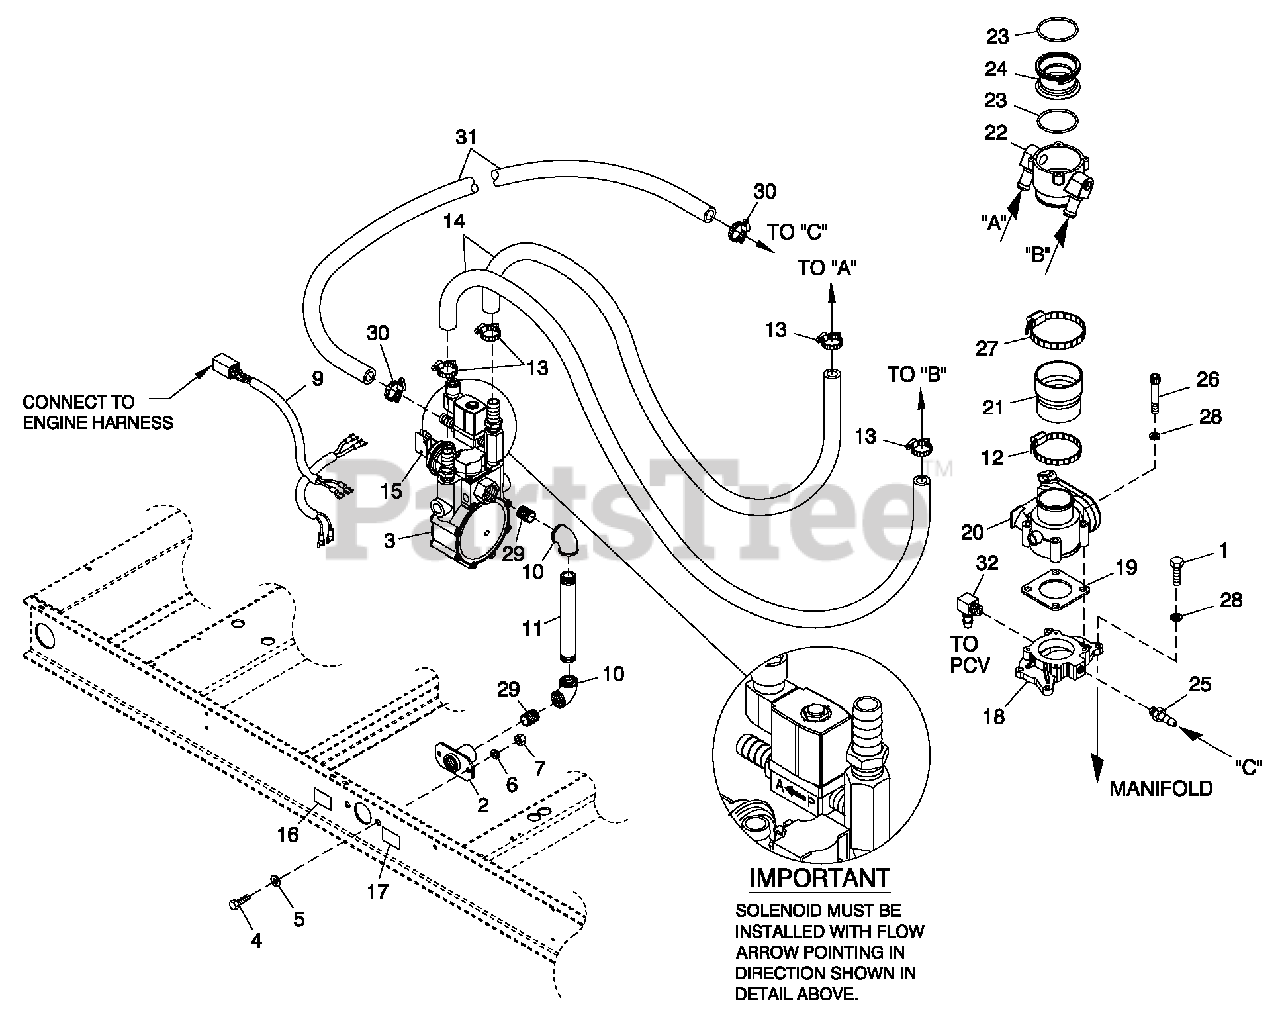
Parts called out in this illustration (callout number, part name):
1	SCREW HHC M6-1.0 X 25 G8.8
2	FLANGE FUEL INLET
3	ASSY REGULATOR 5.4L 55KW NG
4	SCREW HHC M8-1.25 X 20 G8.8
5	WASHER FLAT 5/16-M8 ZINC
6	WASHER LOCK M8-5/16
7	NUT HEX M8-1.25 G8 CLEAR ZINC
9	HARNESS FUEL JUMPER SINGLE REG
10	ELBOW 90D 3/4 NPT
11	NIPPLE PIPE 3/4 NPT X 7"
12	CLAMP HOSE #36 1.88-2.75
13	CLAMP HOSE #10 .56-1.06
14	HOSE 3/4 ID SAE-30R2 (38.5" LG)
15	SWITCH PRESSURE GAS 5" RISE
16	DECAL INLET PRESSURE
17	DECAL FUEL INLET NG (NATURAL GAS APPLICATION)
18	MACHINING INTAKE ADAPTOR 40MM
19	GASKET BOSCH 32 & 40
20	ACTUATOR BOSCH 40 GOVERNOR
21	REDUCER RUBBER 3.0"-2.00"
22	MIXER, 40/60MM ACTUATOR ASSY
23	O-RING 2-3/4 X 3/32 X 2-15/16
24	VENTURI THROTTLE 32MM
25	BARBED STR 1/4 NPT X 3/8
26	SCREW SHC M6-1.0 X 45 G12.9
27	CLAMP HOSE #44 2.31-3.25
28	WASHER LOCK M6-1/4
29	NIPPLE CLOSE 3/4 X 1.375
30	CLAMP HOSE .38-.87
31	HOSE 3/8 ID SINGLE BRAID (36" LG)
32	BARBED EL 90 1/4 NPT X 3/8
